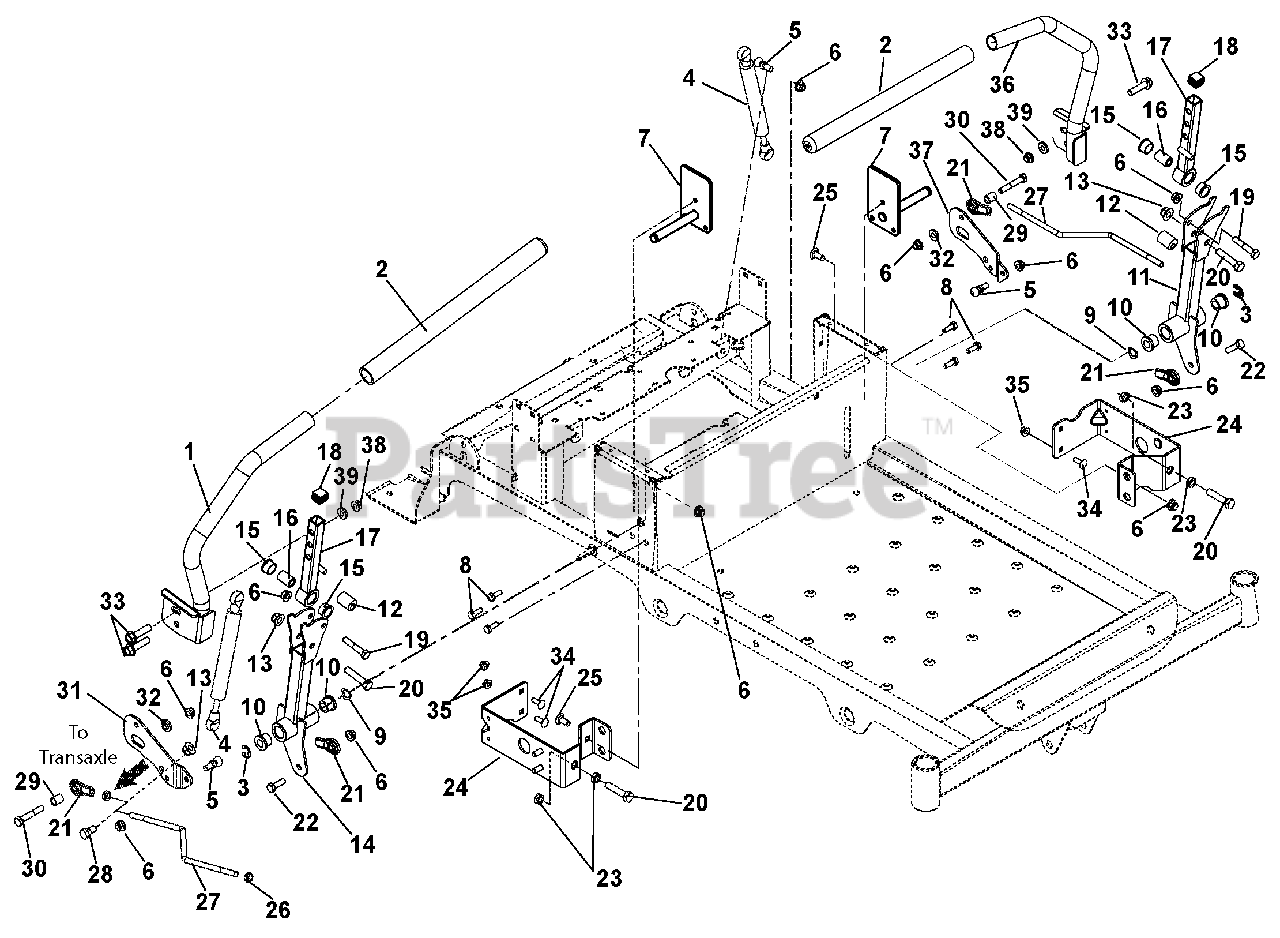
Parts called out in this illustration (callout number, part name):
1	Weldment, Steering Handle Right Hand
2	Grip, Handlebar 15" Foam
3	Ring, Retaining External .438 x 1.00 x 0.83
5	Stud, Ball
6	Nut, .31-18 Flange
7	Weldment, Steering Shaft
8	Screw, Tapping .25-20 x .50 Hex Washer Head
9	Washer, Wave
10	Bushing, Flanged
11	Weldment, Lower Control Arm, Left Hand
12	Bushing, Eccentric
13	Nut, .38-16 Nyloc Flange
14	Weldment, Lower Control Right Hand
15	Bushing, Flanged
16	Spacer, .375 x .625 x .970
17	Weldment, Upper Control Arm
18	Cap Plug, Square
19	Bolt, Hex .31-18 x 1.75
20	Bolt, Hex .375-16 x 1.75
21	Alignaball, 5/16 RH Thread
22	Bolt, Hex .31-18 x 1.00
23	Nut, Hex Jam .375-16
24	Bracket, Speed Adjustment/Seat Pivot
25	Bolt, Round Head Square Neck .31-18 x .75
26	Nut, Jam, .31-24
27	Wireform, Steering Link
28	Bolt, Hex .38-16 x .75
29	Spacer, .328 x .500 x .625
30	Bolt, Hex .31-18 x 2.00
31	Plate, Dampener Right Hand
32	Bushing, Flanged
33	Bolt, Serrated Hex Flange Washer Head .375-16 x 1.25
34	Bolt, Round Head Square Neck .25-20 x .75
35	Nut, Locking Nylon Flange .25-20
36	Weldment, Steering Handle Left Hand
37	Plate, Damper Left Hand
38	Nut, Locking Center Jam .375-16
39	Washer, Flat Steel .406 x .812 x .065
